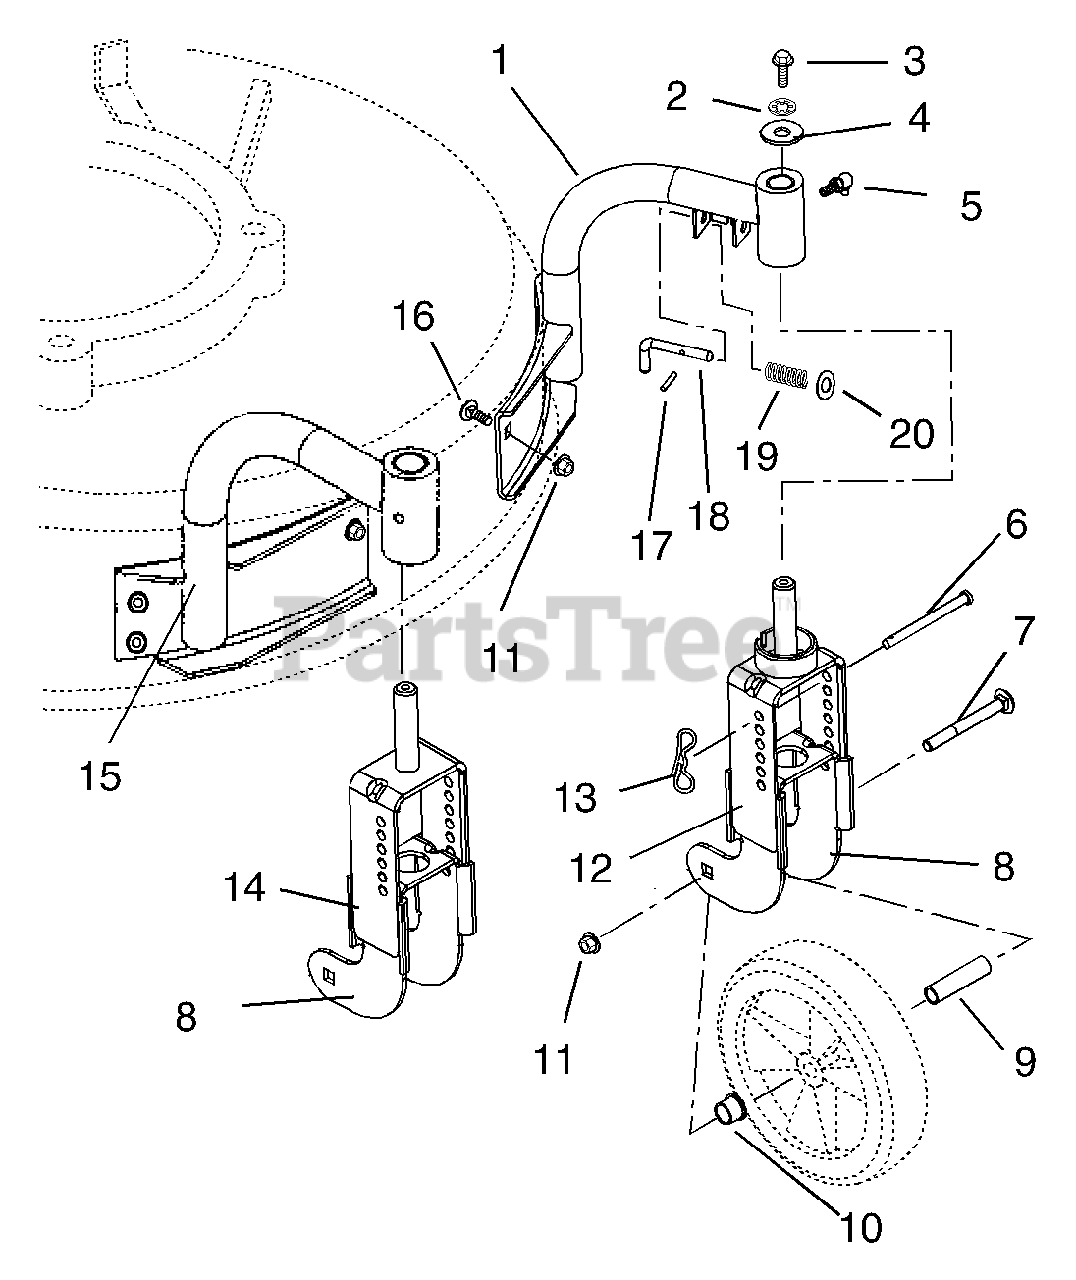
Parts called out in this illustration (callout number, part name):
1	Left Mount
2	1/4" Lock Washer
3	1/4" x 3/4" Hex Bolt
4	9/32" x 1" Flat Washer
5	Lube Fitting
6	Height Adjustment Pin
7	5/16" x 2-3/4" Round Head Square Neck Bolt
8	Inner Yoke
9	Wheel Spacer
10	Flange Bushing
11	5/16" Locknut
12	Left Outer Yoke
13	Bow Tie Locking Cotter Pin
14	Right Outer Yoke
15	Right Mount
16	5/16" x 1/2" Round Head Square Neck Bolt
17	Roll Pin
18	Lockout Pin
19	Compression Spring
20	9/32" x 1/16" Flat Washer
